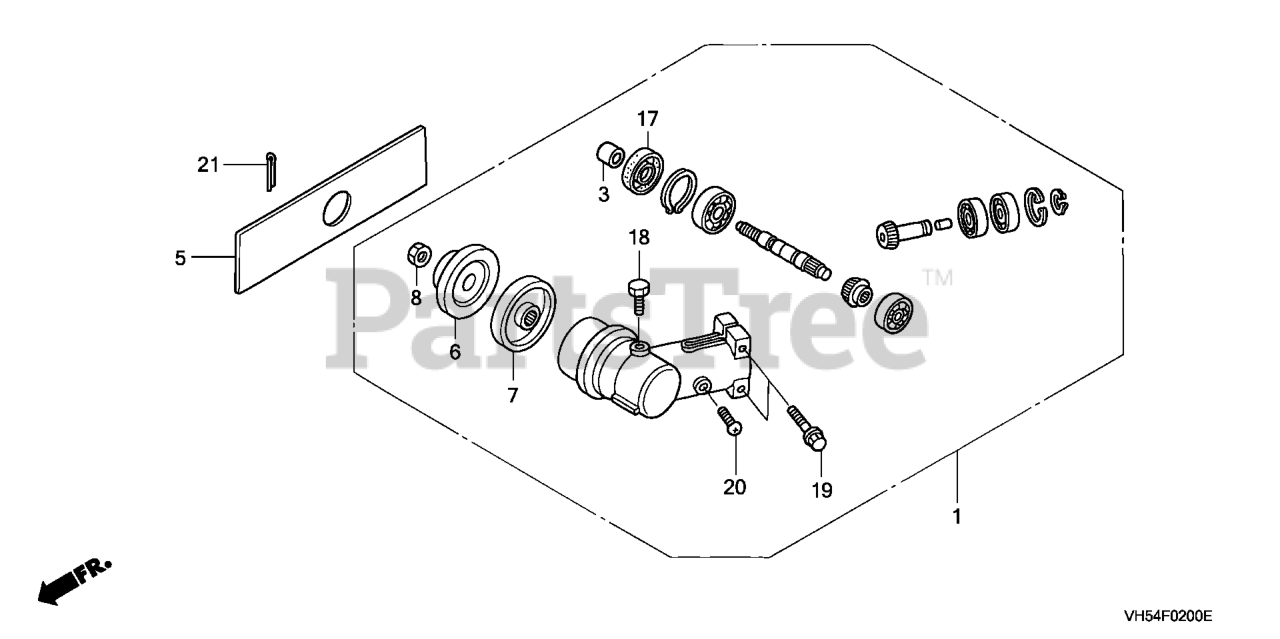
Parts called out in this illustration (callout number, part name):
1	CASE ASSY., GEAR (NOT AVAILABLE)
3	COLLAR, SPLINE
5	BLADE, ROTARY
6	HOLDER A, BLADE
7	HOLDER B, BLADE
8	NUT, HEX. (M10)
18	BOLT, HEX. (8X10)
19	BOLT-WASHER (5X25)
20	SCREW-WASHER (5X12)
21	PIN, COTTER (2.0X22)
21	PIN, COTTER (2.0X35)
